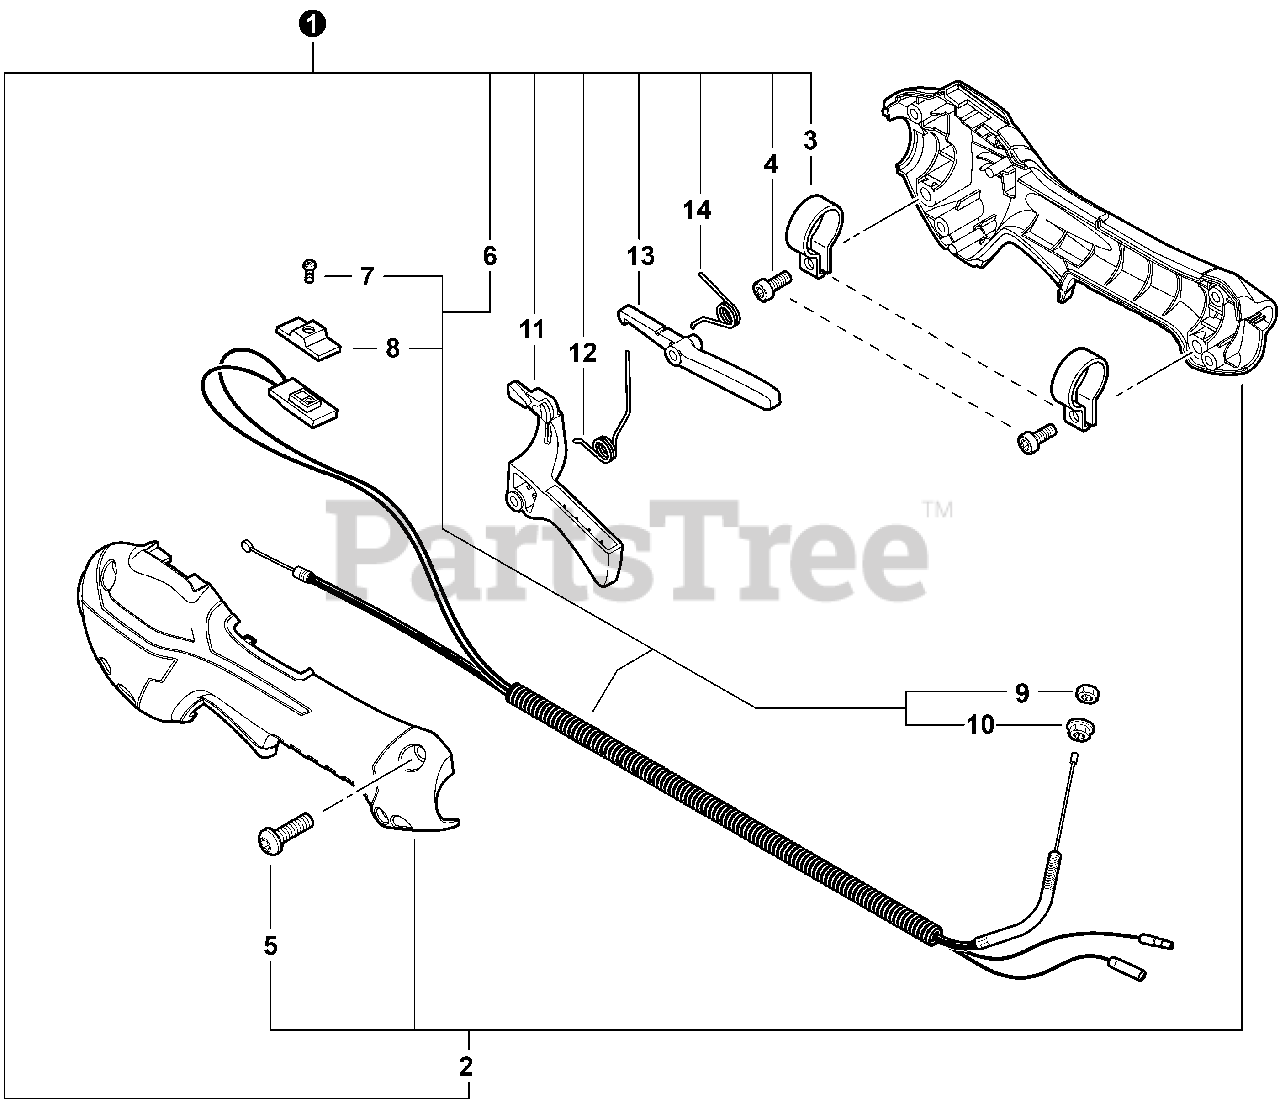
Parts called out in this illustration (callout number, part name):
1	CONTROL HANDLE ASSY
2	CONTROL HANDLE KIT
3	SCREW - 5×16
5	SCREW - 5×16
6	SPRING, LOCKOUT LEVER
7	LEVER, THROTTLE LOCKOUT
8	SPRING, TRIGGER
9	TRIGGER, THROTTLE
10	CONTROL CABLE ASSY
11	SCREW - 3×10
12	KNOB, SWITCH - ORANGE
14	NUT - 6, FLANGE
